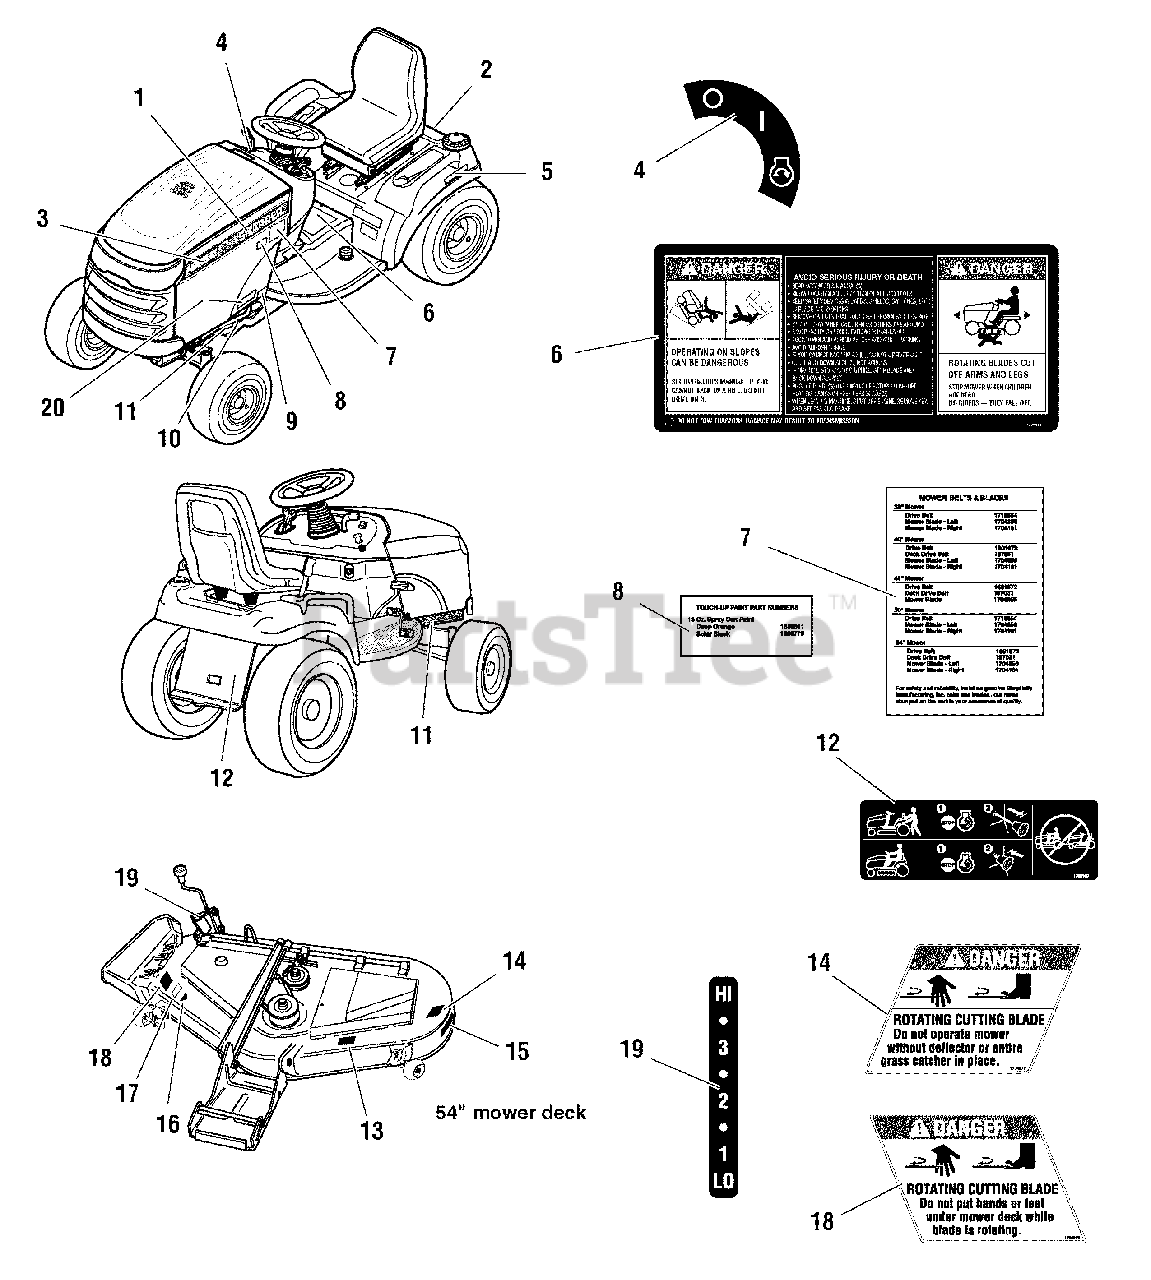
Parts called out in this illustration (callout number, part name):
1	DECAL, Snapper
2	DECAL, Hood Stripe, Snapper, LH
2	DECAL, Hood Stripe, Snapper, RH
3	DECAL, GT500-25HP
4	DECAL, Ignition Switch Symbols, White/Black
5	DECAL, Automatic Control Traction
6	DECAL, Tunnel Cover, Danger Slopes/Blades
7	DECAL, Drive Belts, Mower Blades
8	DECAL, Touch Up Paint, Red
9	DECAL, Protective Sticker
10	DECAL, I.D. Plate
11	DECAL, Patent
12	DECAL, Transmission Release Valve
13	DECAL, I.D. Plate
14	DECAL, Danger Do Not Operate Without Deflector
15	DECAL, Free Floating Mower, Silver
16	DECAL, OPEI Certified
17	DECAL, 54", Silver on Black with Stripe
18	DECAL, Danger Do Not Put Hands/Feet in Mower
19	DECAL, 1 2 3 4 5 6, Height of Cut
20	DECAL, Power Steering
